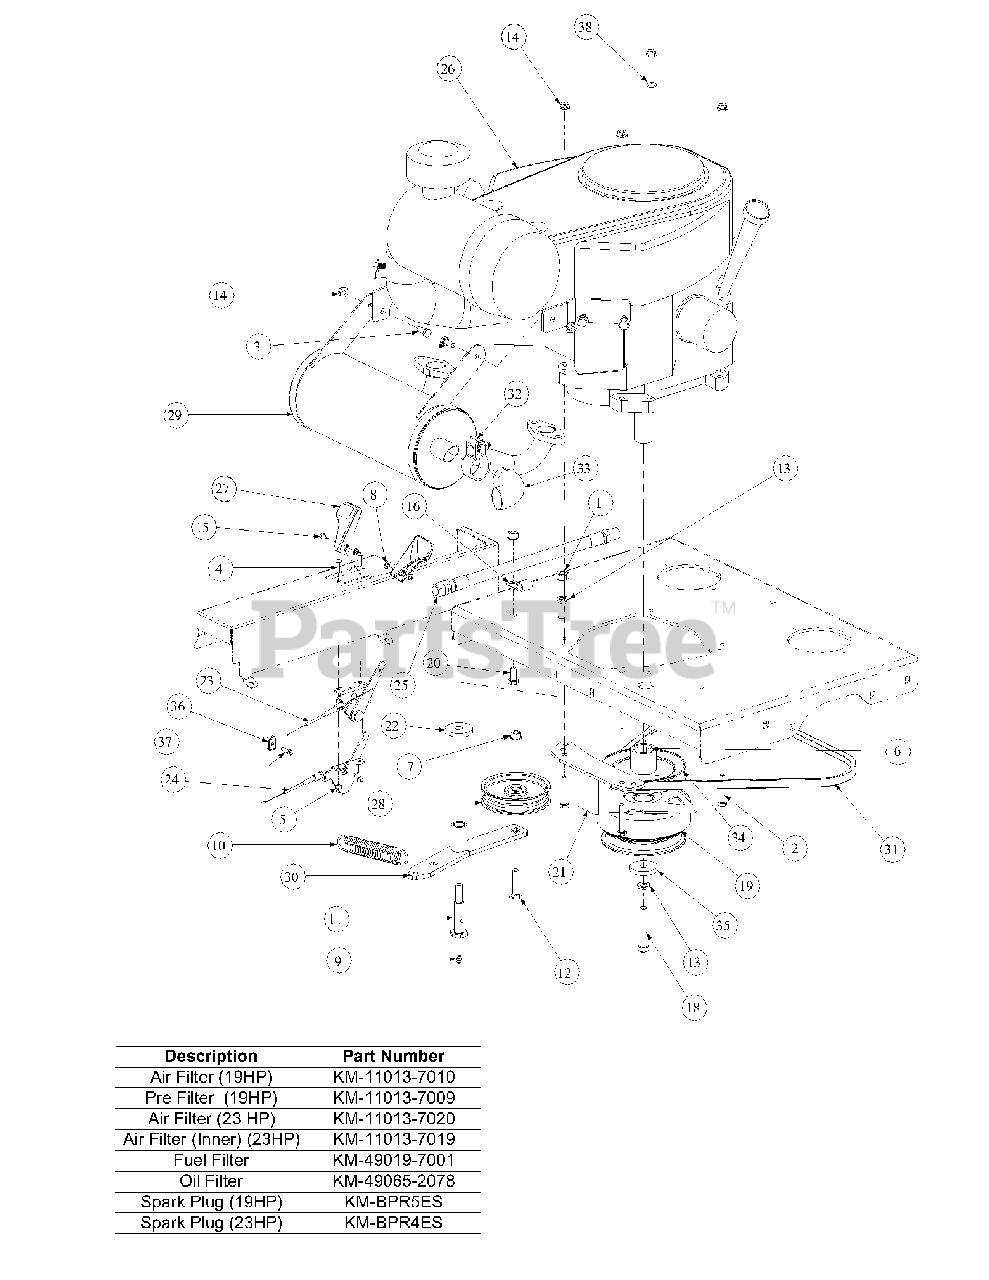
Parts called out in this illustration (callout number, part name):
1	Hex Nut, 7/16-14
2	HHCS, 5/16-18, 1-3/4
3	Hex Cap Screw, 5/16-18 x 3/4
4	Round Hd. Machine Screw, 10-32 x 3/4
5	Lock Nut, Nylon Insert, 10-32
6	Key, 1/4 x 1/4 x 3
7	Flange Lock, Hex Nut, 3/8-16
8	Nut Washer, W/Star, 8-32
9	Grease Fitting, 1/4-28 x 3/16
10	Extension Spring, 1.0 OD x 5.125
11	Shoulder Screw, 7/16-14
12	Hex Carriage Screw, 3/8-16, 1.75
13	Lock Washer, 7/16
14	Hexflange Lock Nut, 5/16-18
15	Machine Screw, 8-32, .375
16	Clip, Heat Shield Cable
17	Hex Cap Screw, M*-1.25 x 20mm
18	Capscrew, 7/16-20 x 2.50
19	Clutch Brake, 1.125 ID
20	Hex Cap Screw, 3/8-16, .750
21	Retainer Clutch Assembly, Ogura
22	Flat Washer, 7/16 ID x 1.75 OD x .25
23	Choke, Control Cable, 43.0
24	Throttle, Control Cable, 39.0
25	Oil Drain Hose
26	19HP Twin Engine, Kawasaki
27	Control Throttle Knob
28	Flat Pulley with Flanges
29	Muffler Accessory, Kawasaki
30	Engine Idler Arm Assembly
30	Bearing
31	V Belt, A Section x .47.3
32	Tube Clamp, 1.375
33	Muffler Accessory Exhaust Tube
34	Pump Drive Pulley
35	Flat Washer, 7/16 ID x 1.75 OD x .25
36	Bolt, M5 x 18
37	Choke Cable Clamp
38	Flat Washer, .320 ID x .591 OD x .078
